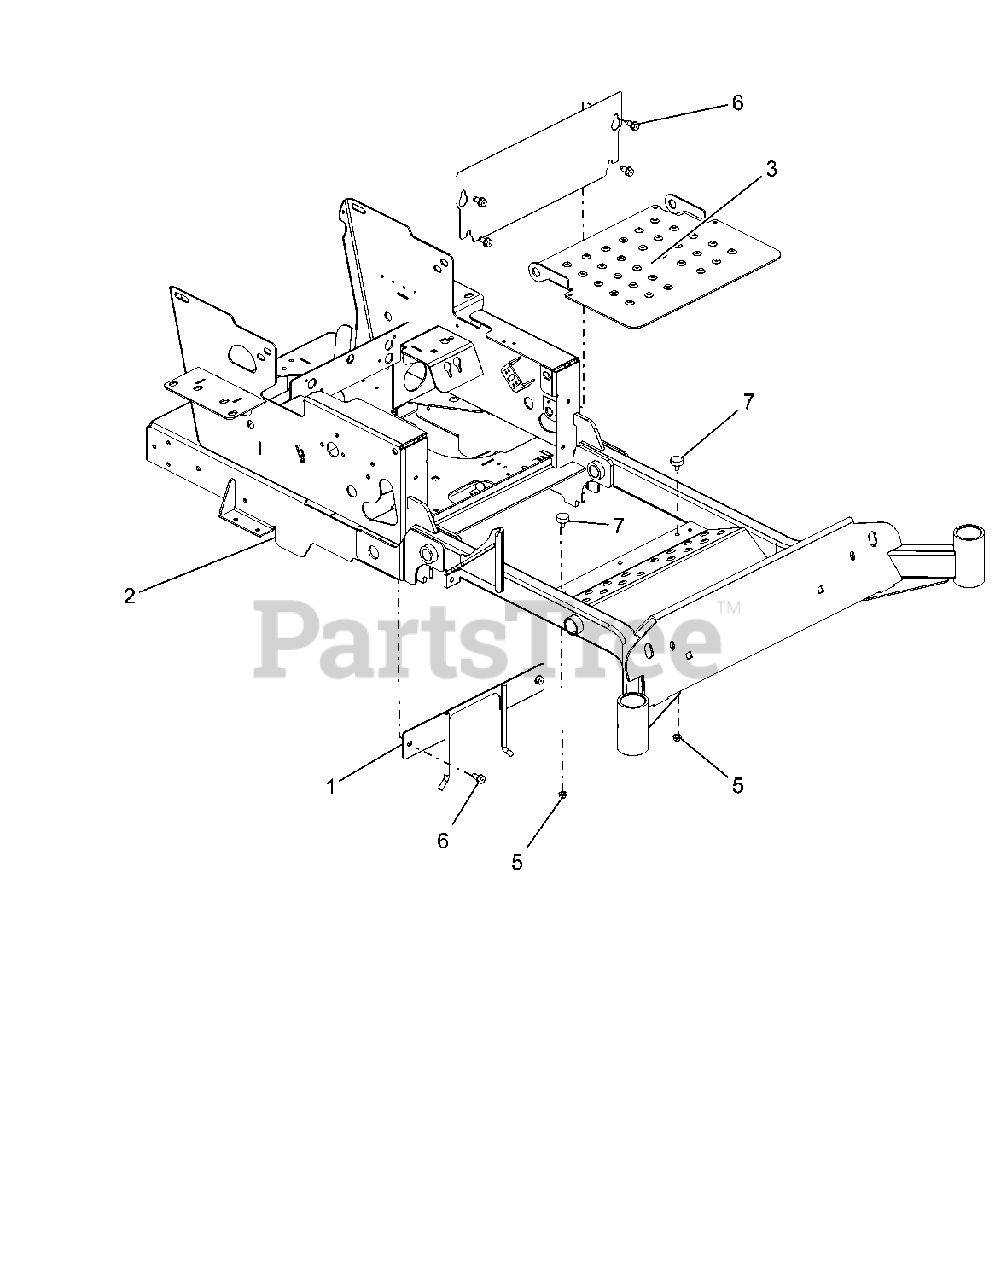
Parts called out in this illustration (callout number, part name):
1	WLDMT, PTO BELT FINGER-BLACK
2	WLDMT, 52"-60" HD FRAME (BLACK)
3	PANEL, INSPECTION
5	@NUT-SPNLK-FLG .312-18 YWZC
6	SCR-TAP .38-16X.75 HWH TR YWZ
7	BUMPER, RUBBER
